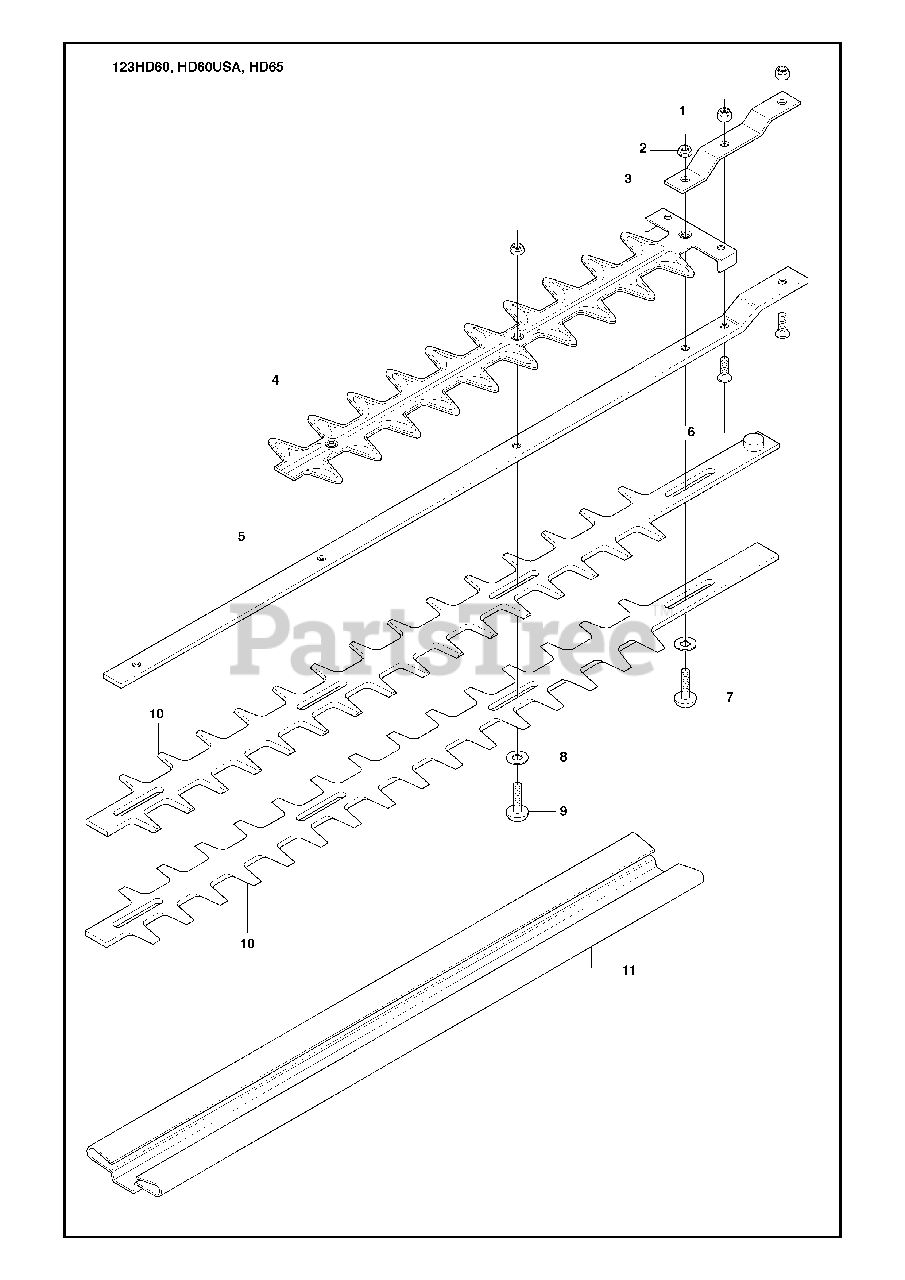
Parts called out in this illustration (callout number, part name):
5	Plate
5	GUIDE PLATE
10	Blade
11	PROTECTOR
11	Cover
